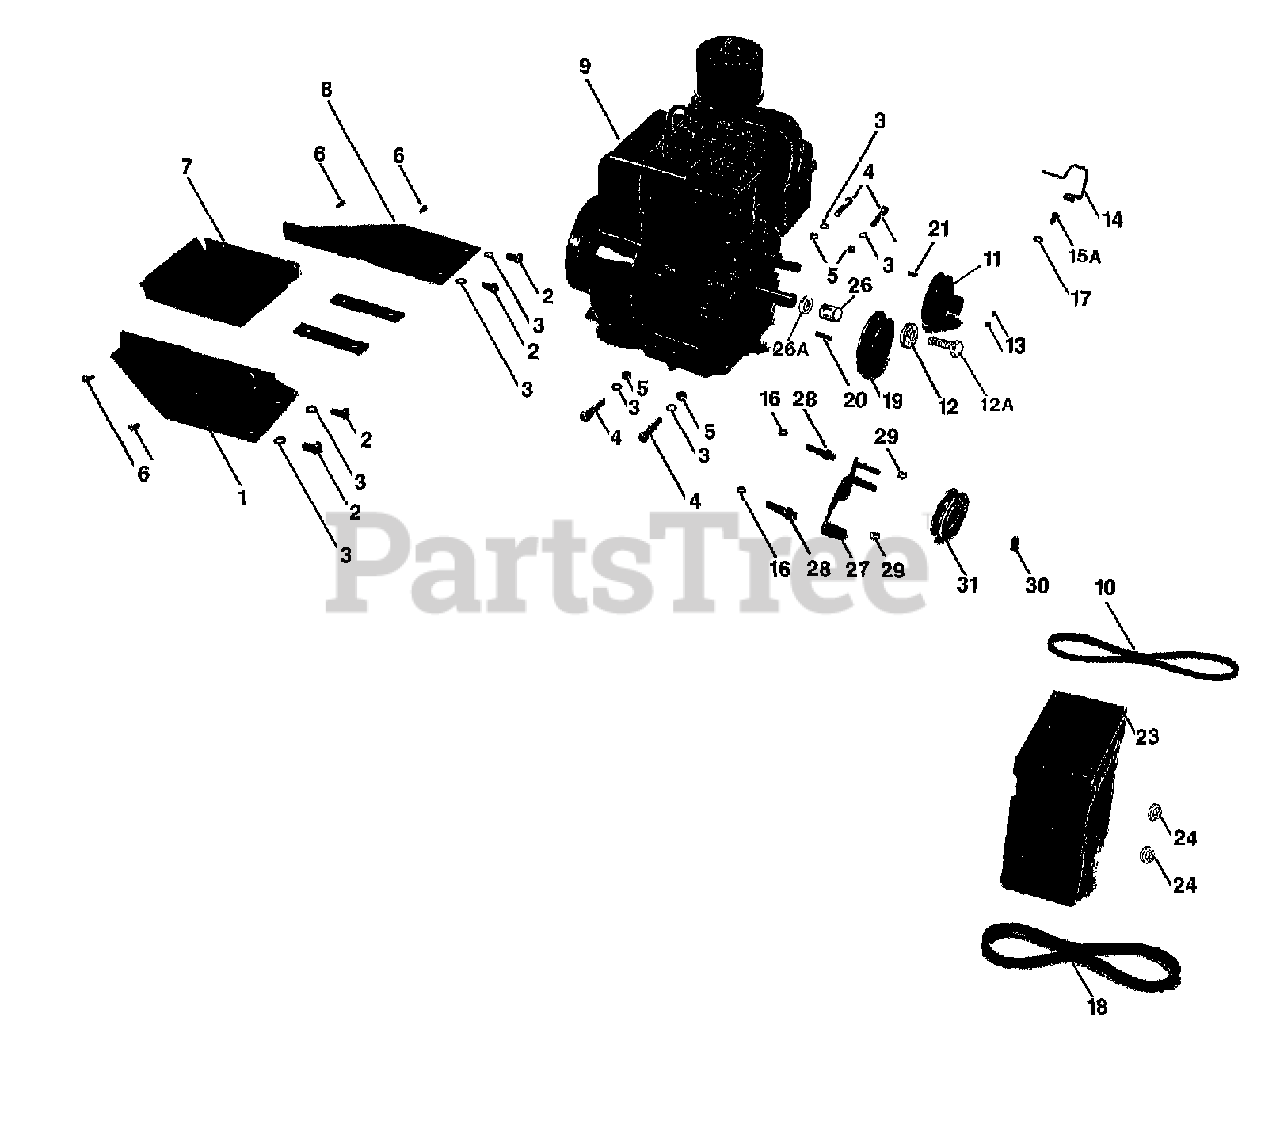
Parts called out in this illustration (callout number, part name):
1	SUPPORT BRACKET-engine, left side
2	BOLT-hex head, 5/16-18 x 3/4", brackets to transmission
3	LOCKWASHER-5/16"
4	BOLT-5/16"-18 x 1 1/2"
5	NUT-hex, 5/16"-18
6	SCREW-hex head, No. 10-32 x 1/2" self-tapping (sems-with permanent washer)
7	SUPPORT BRACKET(PAN)-engine,front
8	SUPPORT BRACKET-engine, right side
10	V-BELT-Reverse
11	REVERSE PULLEY- engine driven, one groove, single belt
12	WASHER- disc spring (concave surface faces forward pulley)
12A	BOLT-hex head 5/16"-24 x 3/4" (attaches forward pulley), Grade 5
13	SET SCREW- socket head, 1/4"-20 x 1/4",(secures reverse engine pulley)
14	BELT GUIDE- forward drive belt
15A	BOLT-hex head, 1/4"-20 x 3/4", self-tapping
16	LOCKWASHER-1/4"
17	WASHER-plain (flat), 1/4", S.A.E
18	V-BELT-forward
19	FORWARD PULLEY-engine driven, one groove, single belt
20	KEY -3/16" square x 1", forward pulley to forward PTO shaft
21	KEY- Woodruff (size #5),reverse pulley to reverse PTO shaft
23	COVER -shields belts and pulleys
24	NUT-5/16"-18, locking, whiz-style
26	SPACER (on forward PTO shaft between engine and forward pulley)
26A	SHIM (on forward PTO shaft between engine and spacer)
27	MOUNTING BRACKET- reverse idler pulley
28	STUD-engine, reverse idler pulley mounting bracket (Briggs & Stratton part)
29	LOCKNUT-1/4"-20
30	LOCKNUT-3/8"-16
31	PULLEY-Reverse Idler (internal bushing type)
